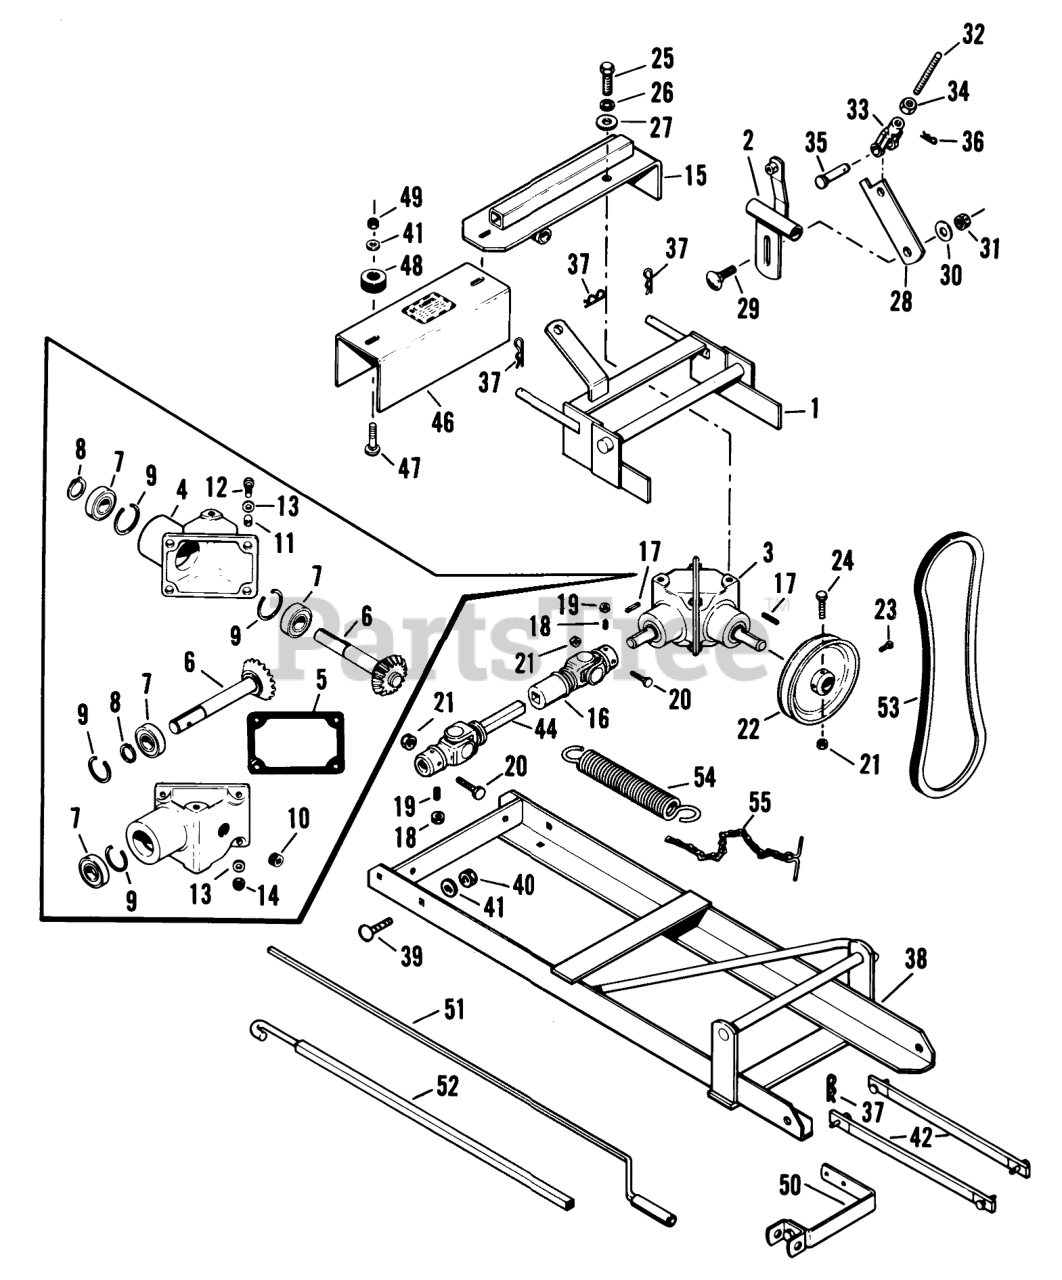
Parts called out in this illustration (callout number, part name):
1	ASSEMBLY-BRACKET
2	Bracket-Gearbox Actuating
3	Assembly-Gearbox
4	Gearbox Case Half
5	Gasket
6	Assembly-Shaft & Gear
7	BEARING-GEAR BOX
8	RING-SNAP
9	Ring-Snap
10	PLUG PIPE
11	BUSHING
12	Bolt 5/16-18 x 11/4
13	Washer
14	Nut 5/16-18 Keps
15	Assembly-Gearbox Mtg.
16	Slip Assembly-Female End
18	Screw-Set (3/8-16 x 5/8 Allen Hd. Cup Pt.
19	3/8-16 Jam Nut
20	Bolt 1/4-20 x 2
22	Pulley
23	Screw-Set (5/16-18 x 1/2 Square Head)
24	Bolt Hex 1/4-20 x 1 3/4
25	Bolt 3/8-16 x 1
26	Washer
27	Lockwasher
28	NDNK-OVER CENTER
29	Bolt-1/2-13 x 1-1/2 Carr.
30	Washer
31	Nut-ES 1/2-13
32	Stud
33	Clevis
34	Nut-3/8-24 Lt.
35	Clevis Pin
36	PIN-HAIR
37	Pin
38	Mounting Frame
39	Bolt-3/8-16 x 3/4
40	Nut, Jam, 3/8-24 Thd
41	Washer
42	Lift Bar
44	Slip Assy.-Male End
46	PTO Cover
47	Bolt-Carriage
48	Rubber Washer
49	3/8-16 E.S.
50	Crank Rod Support Assembly
51	Assy.-Crank Rod
52	Crank Rod Extension
53	V-Belt
54	SPRING-EXTENSION
55	Chain and Toggle
